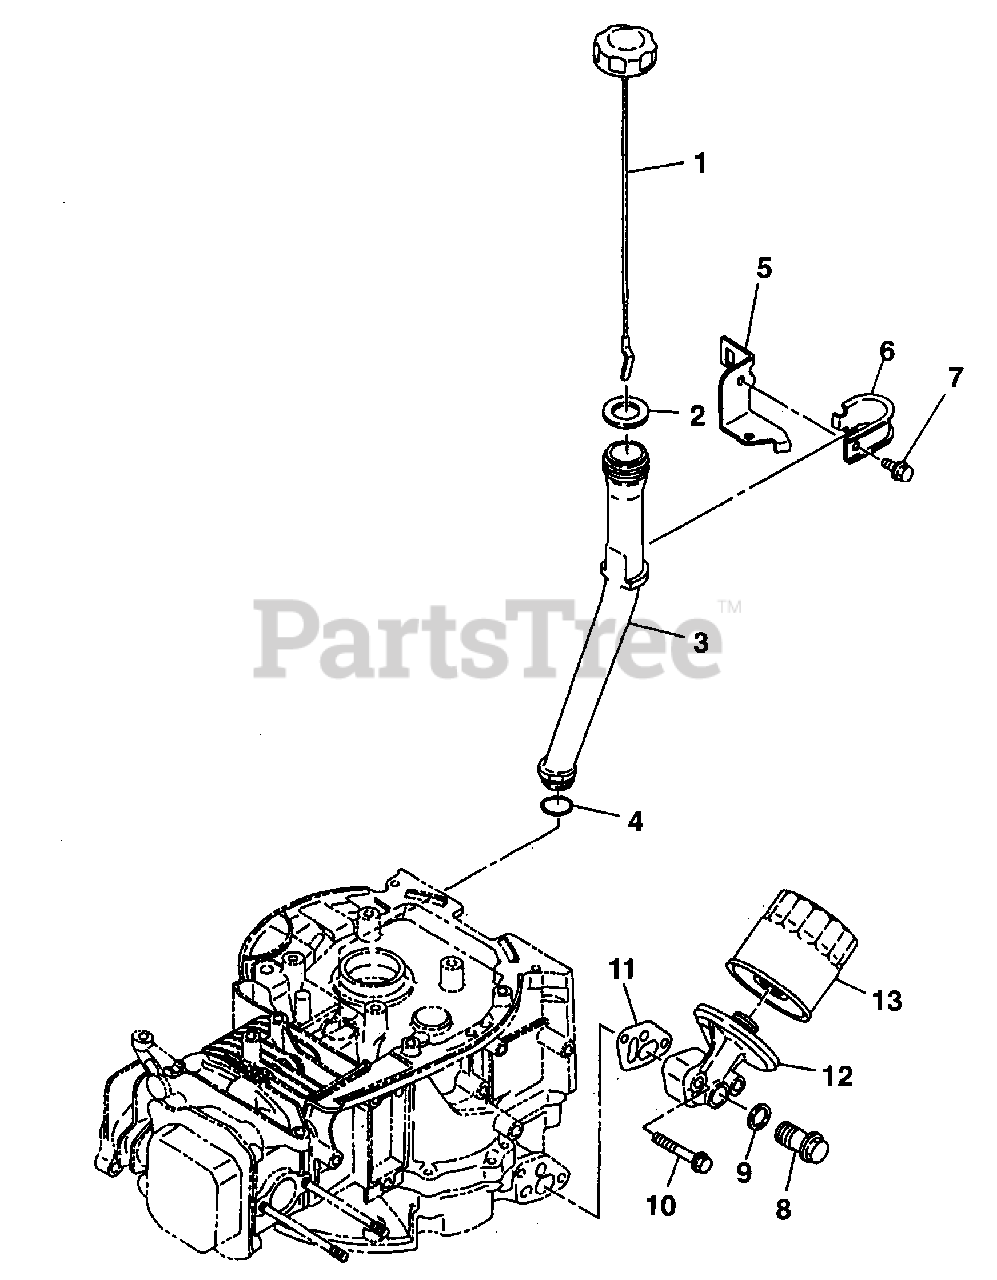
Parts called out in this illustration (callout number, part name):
1	GAUGE, Oil
3	OIL FILLER
5	BRACKET, Oil filler
6	CLAMP, Oil filler
7	BOLT, Flange
8	PLUG, Oil Drain
10	BOLT, Flange
11	GASKET, Oil Filter Brkt
12	BRACKET, Oil Filter
13	FILTER, Oil
